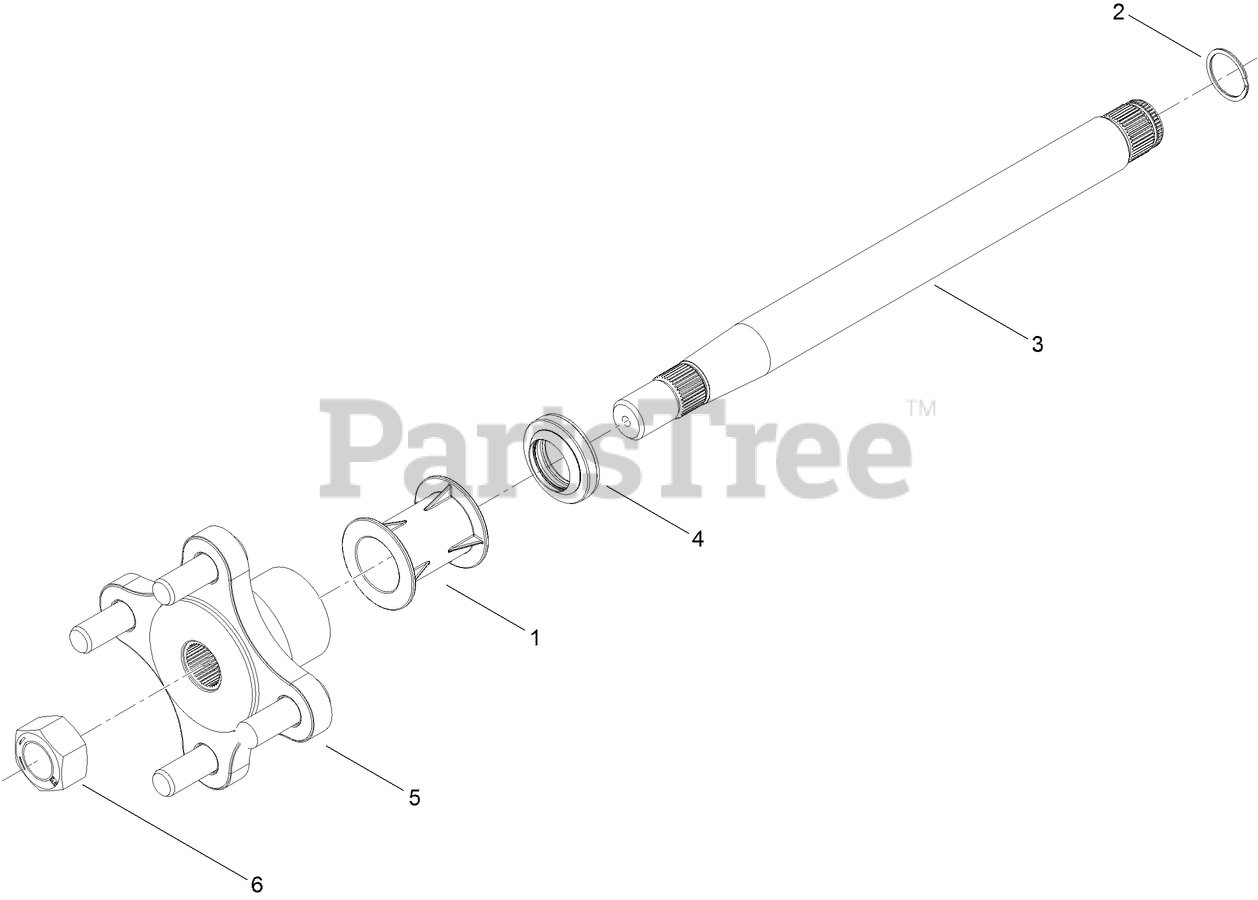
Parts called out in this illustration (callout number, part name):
1	TUBE-AXLE
2	RING-SPIRAL, RETAINING
3	SHAFT-AXLE
4	SEAL-LIP
5	HUB KIT
6	NUT
